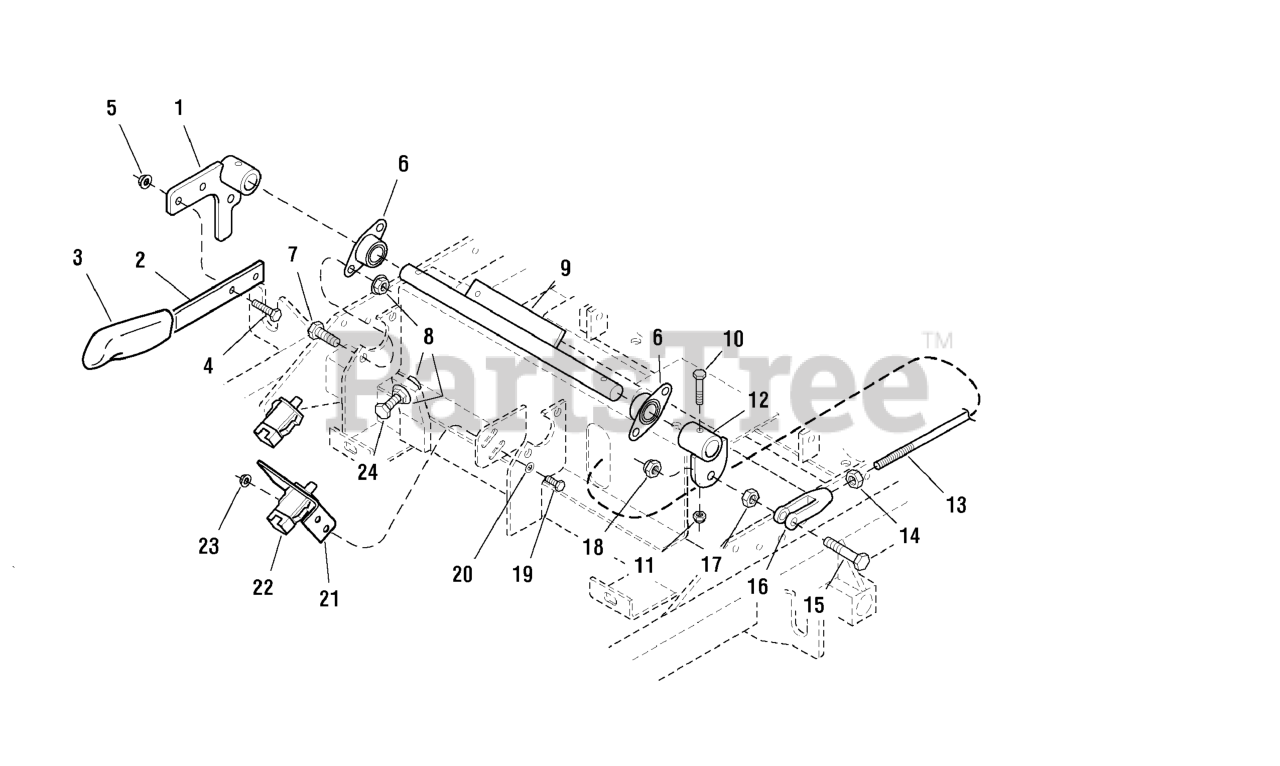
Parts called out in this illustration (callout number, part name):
1	BRAKE HANDLE MOUNT
2	BRAKE HANDLE
3	GRIP
4	BOLT, 5/16-18 X 1 GD5 YZ
5	NUT, 5/16-18 HEX SERRATED FLANGE (SMALL)
6	BEARING, Flange
7	BOLT, 3/8-16 X 3/4" GD5 CZ
8	NUT, 3/8-16 Hex Serrated Flange
9	BRAKE HANDLE SHAFT
10	BOLT, 1/4-20 x 1-3/4
11	NUT, 1/4-20 HEX NYLON LOCK
12	PIVOT, LINKAGE MOUNT WELDMENT - BLK
13	BRAKE CONNECTING ROD
14	NUT, 3/8-24 Hex
15	BOLT, 3/8-16 X 2, GD5, CZ
16	CLEVIS, 3/8-24, Plastic
17	NUT, 3/8-16 Hex
18	NUT, 3/8-16 HEX NYLON LOCK
19	BOLT, 1/4-20 x 3/4
20	WASHER, 1/4 SAE
21	SWITCH MOUNT BRACKET
22	SWITCH (see electrical group)
23	NUT, 1/4-20 HEX SERR. FLANGE
24	BOLT, 3/8-16 x 1-3/4 TFL
